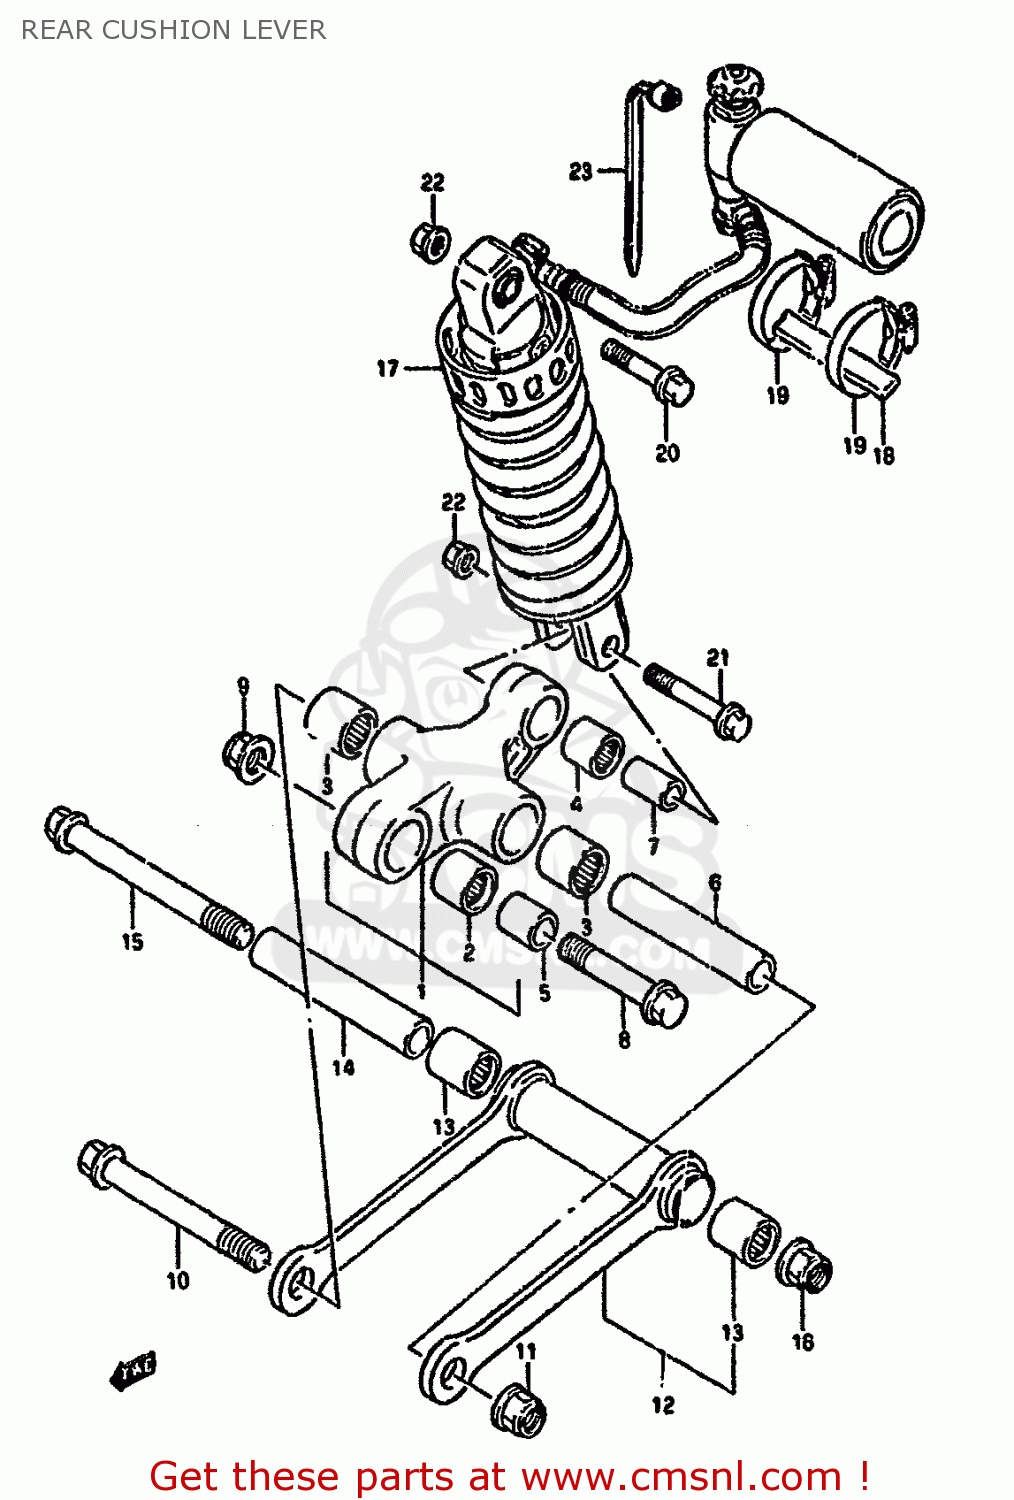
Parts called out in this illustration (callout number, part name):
1	LEVER SET,REAR CUSHION
2	BEARING(20X27X32)
3	BEARING(20X27X23.5)
4	BEARING(17X24X26)
5	SPACER(14X20X34)
6	SPACER(14X20X99)
7	SPACER,REAR CUSHION LEVER
8	BOLT(14X66)
9	NUT 14MM
10	BOLT(14X129)
11	NUT 14MM
12	ROD SET,REAR CUSHION LOWER
13	BEARING(20X27X23.5)
14	SPACER (14X20X129)
15	BOLT(14X159)
16	NUT 14MM
17	ABSORBER ASSY,RR SHOCK
18	CUSHION, RESERVOIR TANK
19	CLAMP
20	BOLT(10X50)
21	BOLT(10X60)
22	NUT 10MM
23	CLAMP(L:165)
